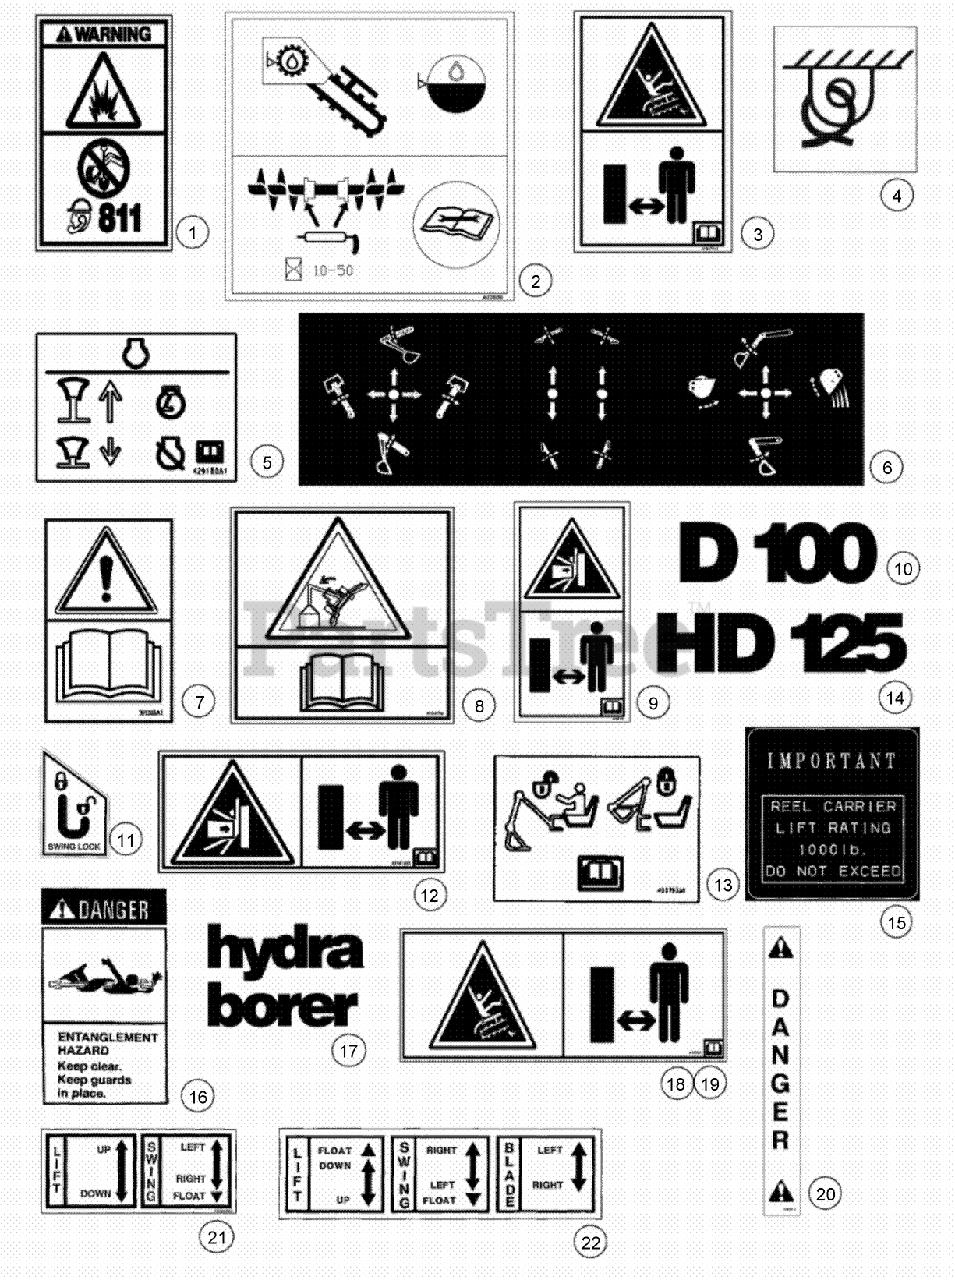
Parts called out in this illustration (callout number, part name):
1	DECAL-Warning, Call Before Digging
2	DECAL-Planetary Oil / Lube Lever
3	DECAL-Danger, Trencher Entanglement Hazard
4	DECAL-Tie Down
5	DECAL-Engine Shut-Off
6	DECAL-Backhoe Control Pattern
7	DECAL-Read Operators Manual
8	DECAL-Warning, Lifting with Backhoe
9	DECAL-Danger, BH Crush Hazard
10	DECAL-D100 BACKHOE-Model Number
11	DECAL-Swing Lock
12	DECAL-Danger, BH Crush Hazard
13	DECAL-BH Transport Lock
14	DECAL-HD125
15	DECAL-Lift Rating (1000 lbs)
16	DECAL-Entanglement
17	DECAL-Model Name
18	DECAL-Danger, Trencher Entanglement Hazard
19	DECAL-Danger, Entanglement Hazard
20	DECAL-Danger
21	DECAL-plow control pattern, lift/swing
22	DECAL-Plow Control
